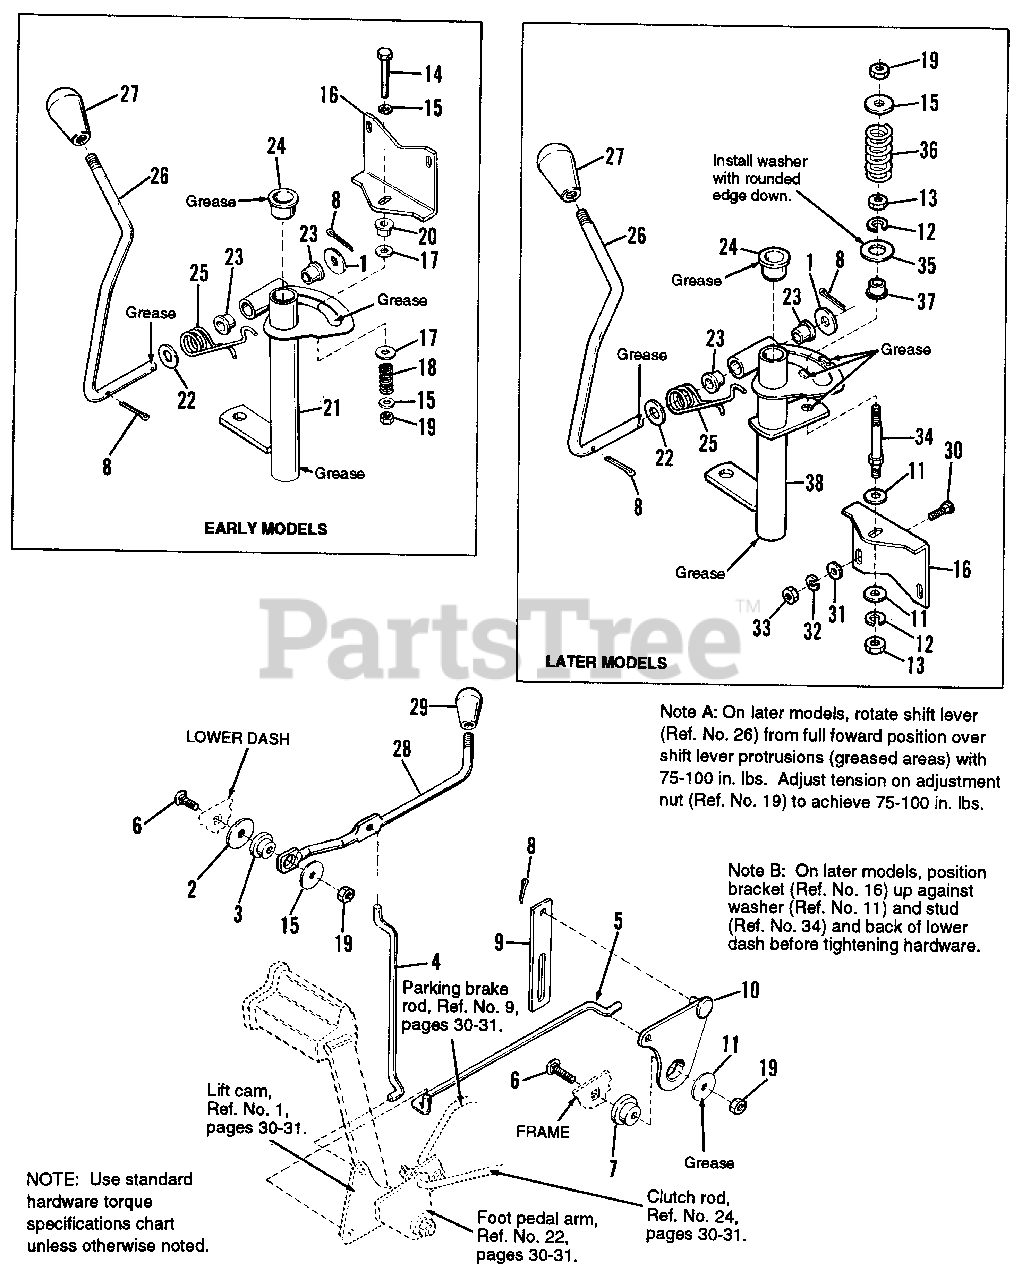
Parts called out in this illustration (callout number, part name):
1	WASHER, 1/2
2	WASHER, Plain, 13/32 x 1-1/2 x 1/8
3	SPACER, Special
4	LINK, Lift Upper
6	CARRIAGE BOLT, 5/16-18 x 1-1/2
7	SPACER, Special
8	COTTER PIN
9	LINK, Lift, Upper Transport
10	CAM, Lift Assy.
11	WASHER, Plain, 21/64 x 1-1/4
12	LOCKWASHER, 5/16
13	NUT, Hex, 5/16-18
14	CAPSCREW, Hex Hd., 5/16-18 x 1-3/4 (Early models only)
15	WASHER, Plain, 5/16
16	BRACKET, Tension
17	WASHER, Plain, 5/8 (Early models only)
18	SPRING (Early models only)
19	NUT, Hex, ESNA Lock, 5/16-18 (Qty. 2 on later models)
21	SHIFT LEVER KIT (Early models only)
22	WASHER, Plain
23	BUSHING, Plastic, 1/2 Dia.
24	BUSHING, Nylon, 3/4 Dia.
25	SPRING, Torsion
26	LEVER, Shift
27	KNOB, Plastic
28	ROD, Lift Handle
29	KNOB
30	CARRIAGE BOLT, 1/4-20 x 3/4
31	WASHER, Plain, 1/4
32	LOCKWASHER, 1/4
33	NUT, Hex, 1/4-20
34	STUD, 5/16-18 x 3-1/4
35	WASHER, H.T.
36	SPRING, Compression (Later models only)
38	SHIFT LEVER ASSY. (Later models only)
